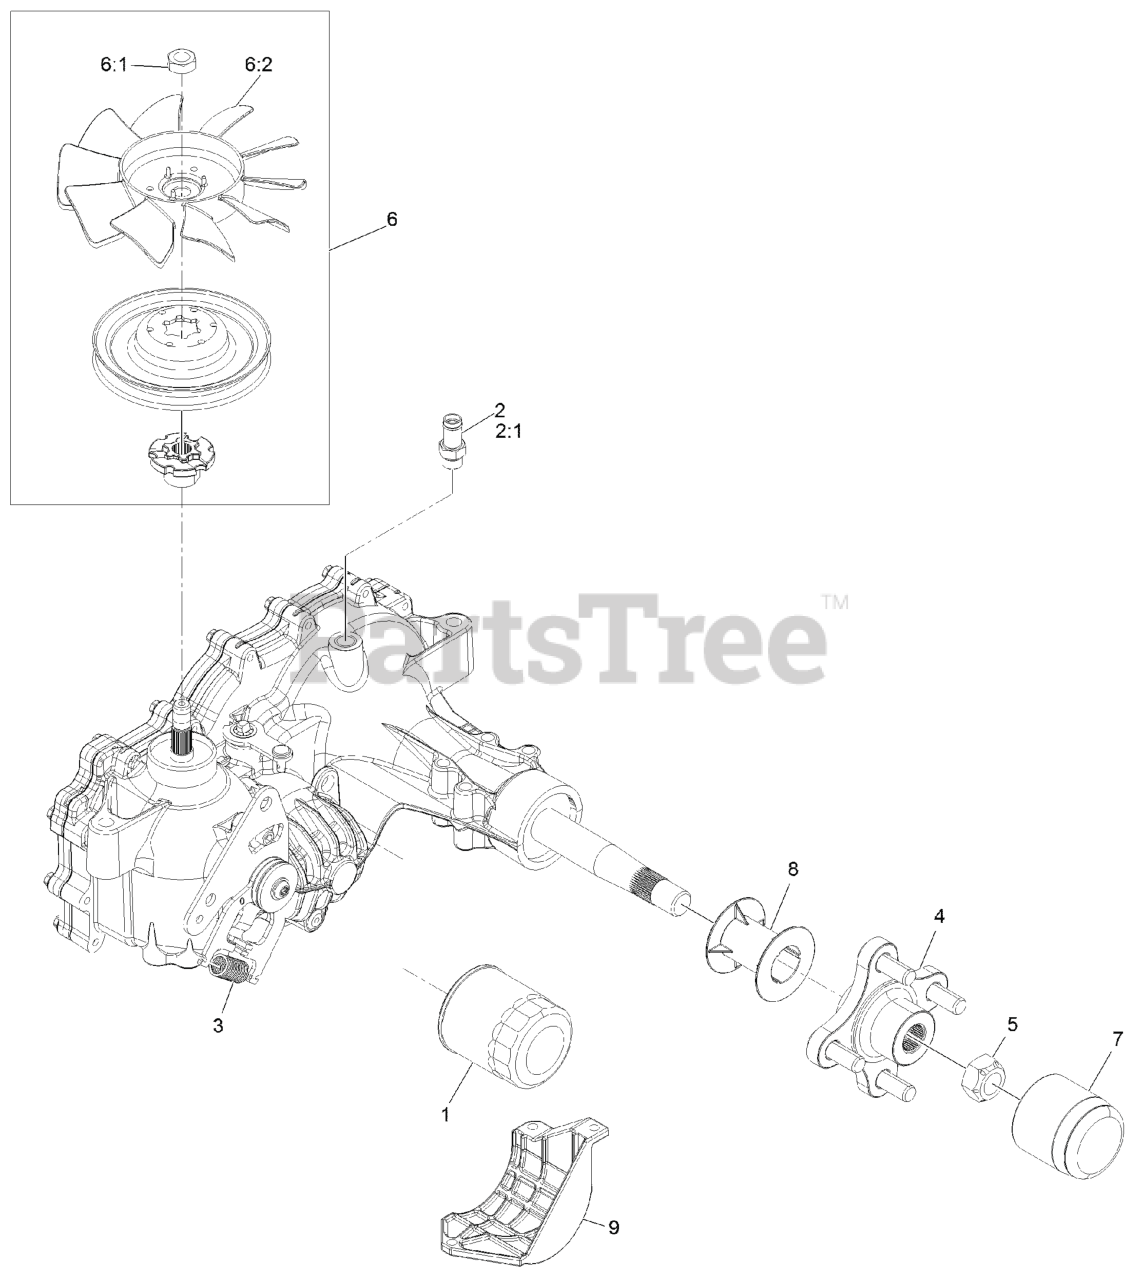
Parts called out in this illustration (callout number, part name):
1	ELEMENT-OIL FILTER, HYD
2	ADAPTER-STRAIGHT
2:1	O-RING
3	SPRING-EXTENSION
4	HUB-OFFSET
5	NUT-HUB
6	Fan And Pulley Kit
7	CAP-AXLE, LONG
8	TUBE-AXLE
9	GUARD-FILTER, LH
